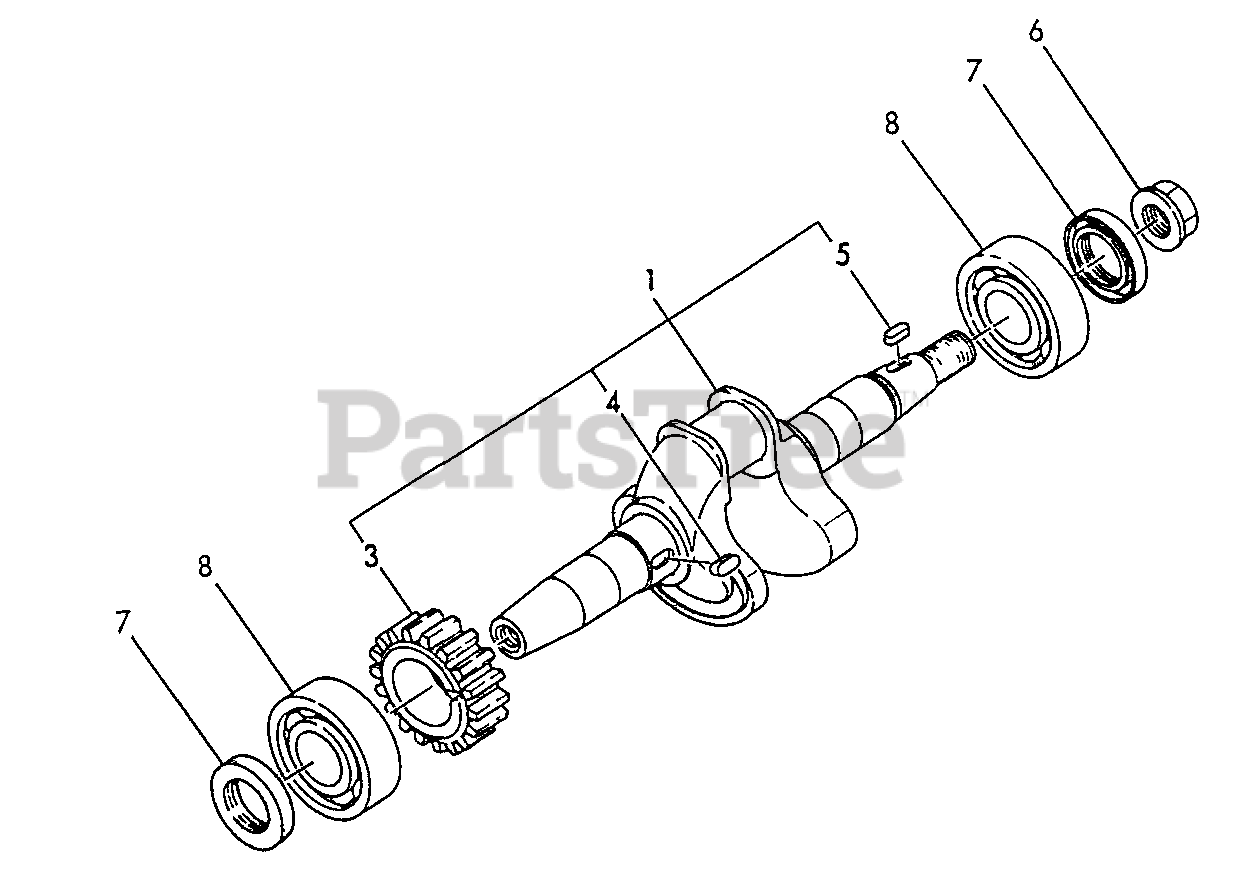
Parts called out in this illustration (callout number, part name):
1	CRANKSHAFT ASSY
3	GEAR, CRANKSHAFT
4	KEY - 4×10
5	KEY - 4×10
6	NUT - 12
7	SEAL, OIL
8	BEARING, BALL 6204 C3
